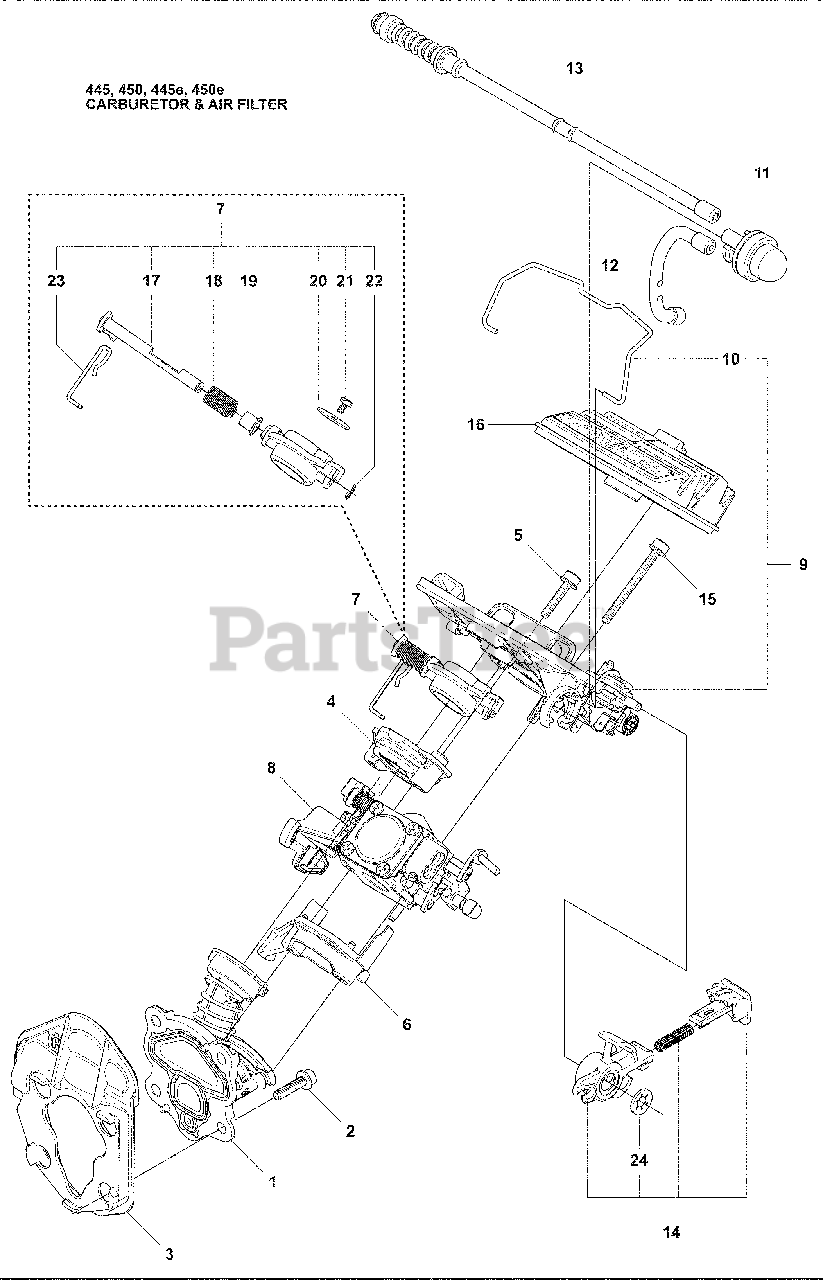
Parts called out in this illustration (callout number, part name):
1	Inlet Pipe Assembly
2	Screw, M5 X 16
3	Intermediate Wall
8	Carburetor
9	Filter Holder Assembly
11	Air Purge Bulb
12	Air Purge Suction Hose
13	Return Hose
16	Air Filter, Nylon 80
16	Air Filter, Nylon
16	Air Filter, Felt
17	Shaft Assembly
24	Lock Washer
